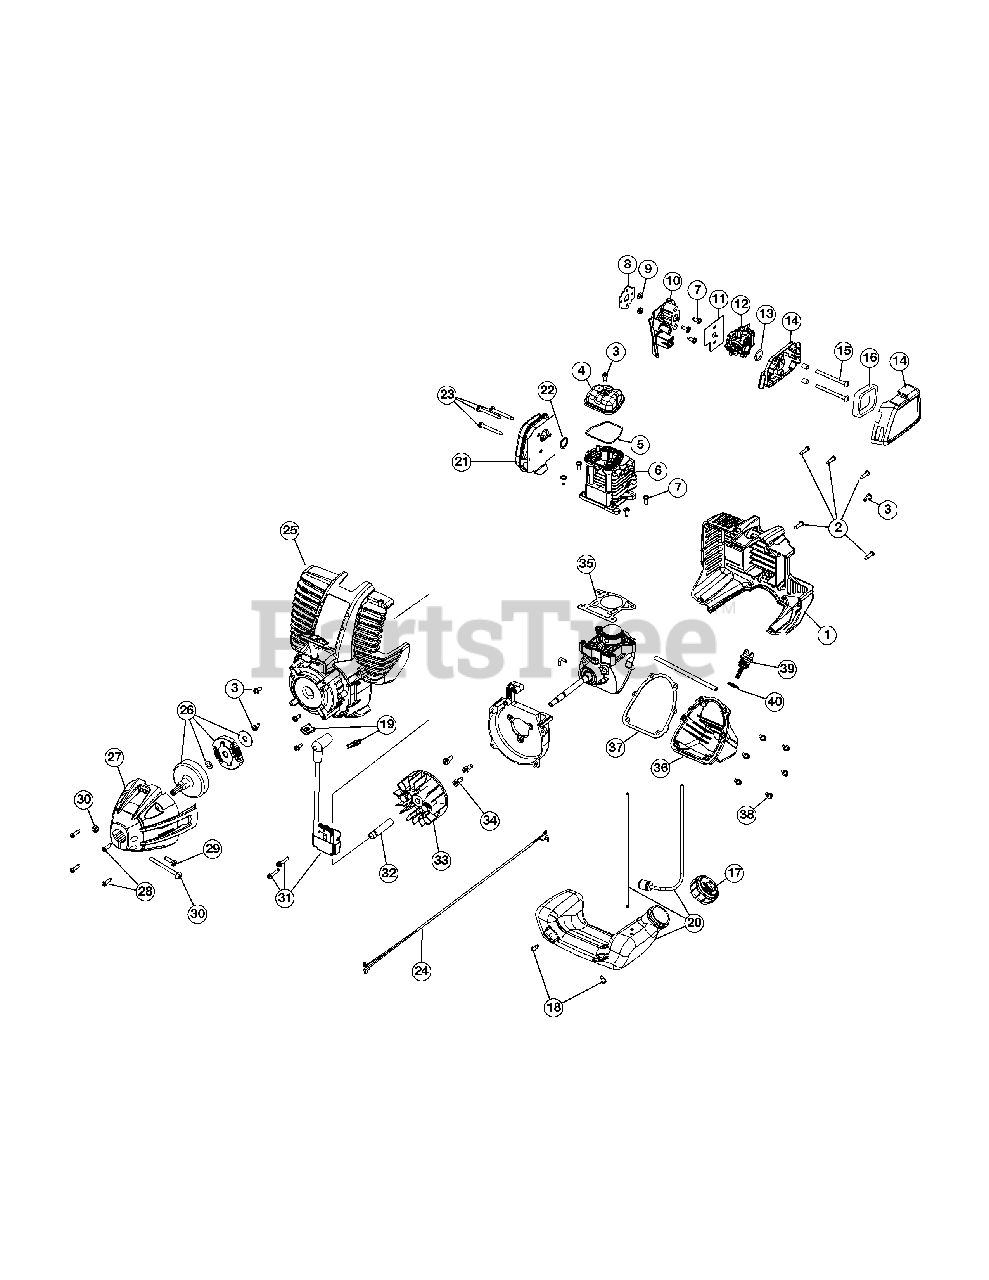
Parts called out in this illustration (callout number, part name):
1	Engine Cover
4	Valve Cover
5	Valve Cover Gasket
6	Cylinder Assembly (Incl. Ref No. 5, 7 & 35)
7	Cylinder Screw
8	Insulator Gasket
10	Insulator (Incl. Ref No. 11)
11	Carburetor Gasket
12	Carburetor w/Primer
13	Carburetor O-Ring
14	Air Filter Cover Assembly (Incl. Ref No. 15 & 16)
15	Air Filter Mounting Screw
16	Air Filter
17	Fuel Cap
19	Clip Nut
20	Fuel Tank Assembly (Incl. Ref No. 17)
21	Muffler Assembly (Incl. Ref No. 22 & 23)
22	Muffler Gasket
23	Muffler Mounting Screw
24	Lead Wire
25	Starter Housing Assembly (Incl. Ref No. 3)
26	Clutch Assembly
27	Clutch Cover Assembly (Incl. Ref No. 28-30)
28	Cover Screw
29	Anti-Rotation Screw
30	Clamping Screw Assembly
31	Module Assembly
32	Spacer
33	Flywheel
34	Shroud Screw
35	Cylinder Gasket
36	Oil Pan (Incl. Ref No. 37 & 38)
37	Oil Pan Gasket
38	Oil Pan Screw
39	Dipstick Assembly (Incl. Ref No. 40)
